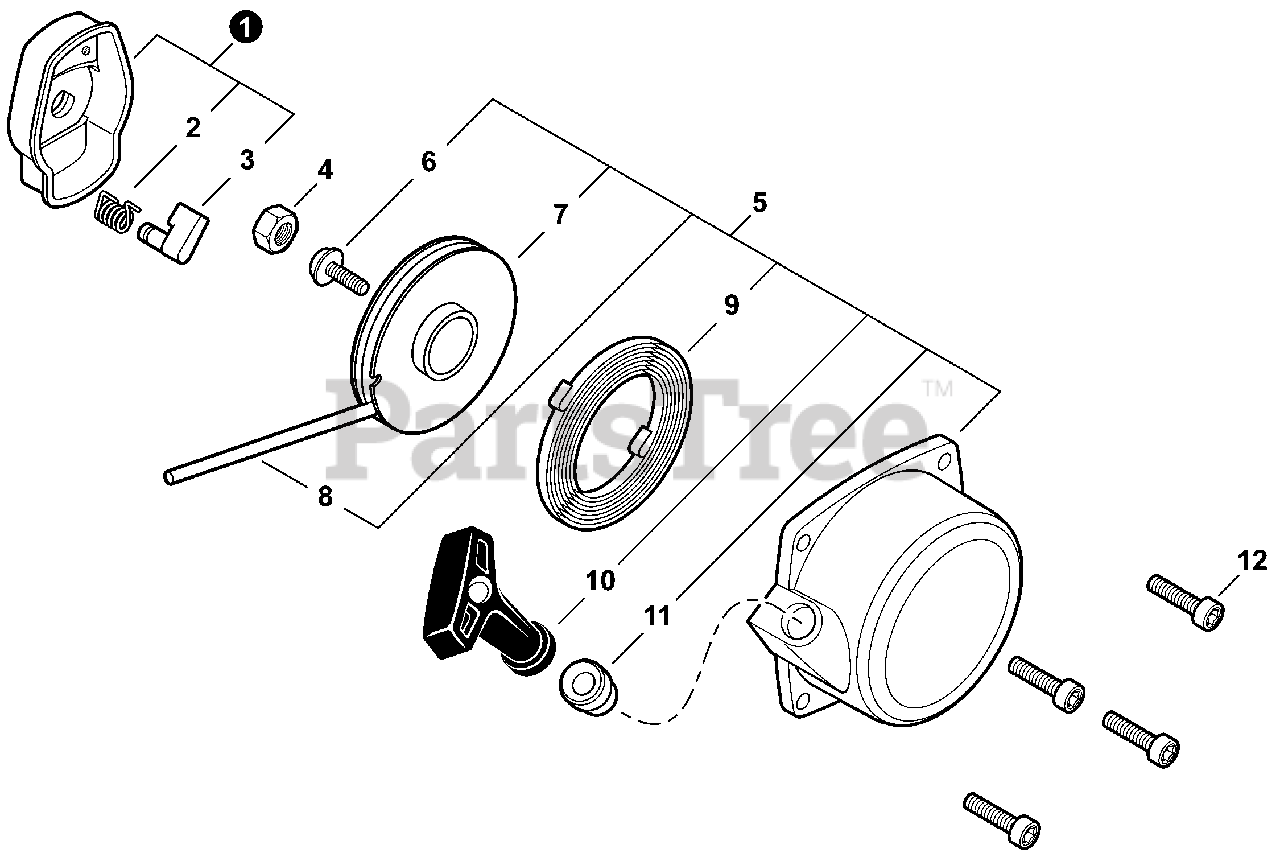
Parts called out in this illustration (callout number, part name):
1	PULLEY ASSY, STARTER
2	SPRING, RETURN
3	PAWL, STARTER - BLACK
5	STARTER ASSY, RECOIL
6	SCREW
7	REEL, ROPE
8	ROPE, STARTER 3.0×1000
9	SPRING, RECOIL
10	GRIP, STARTER
11	GUIDE, ROPE
12	BOLT, TORX 4×16
